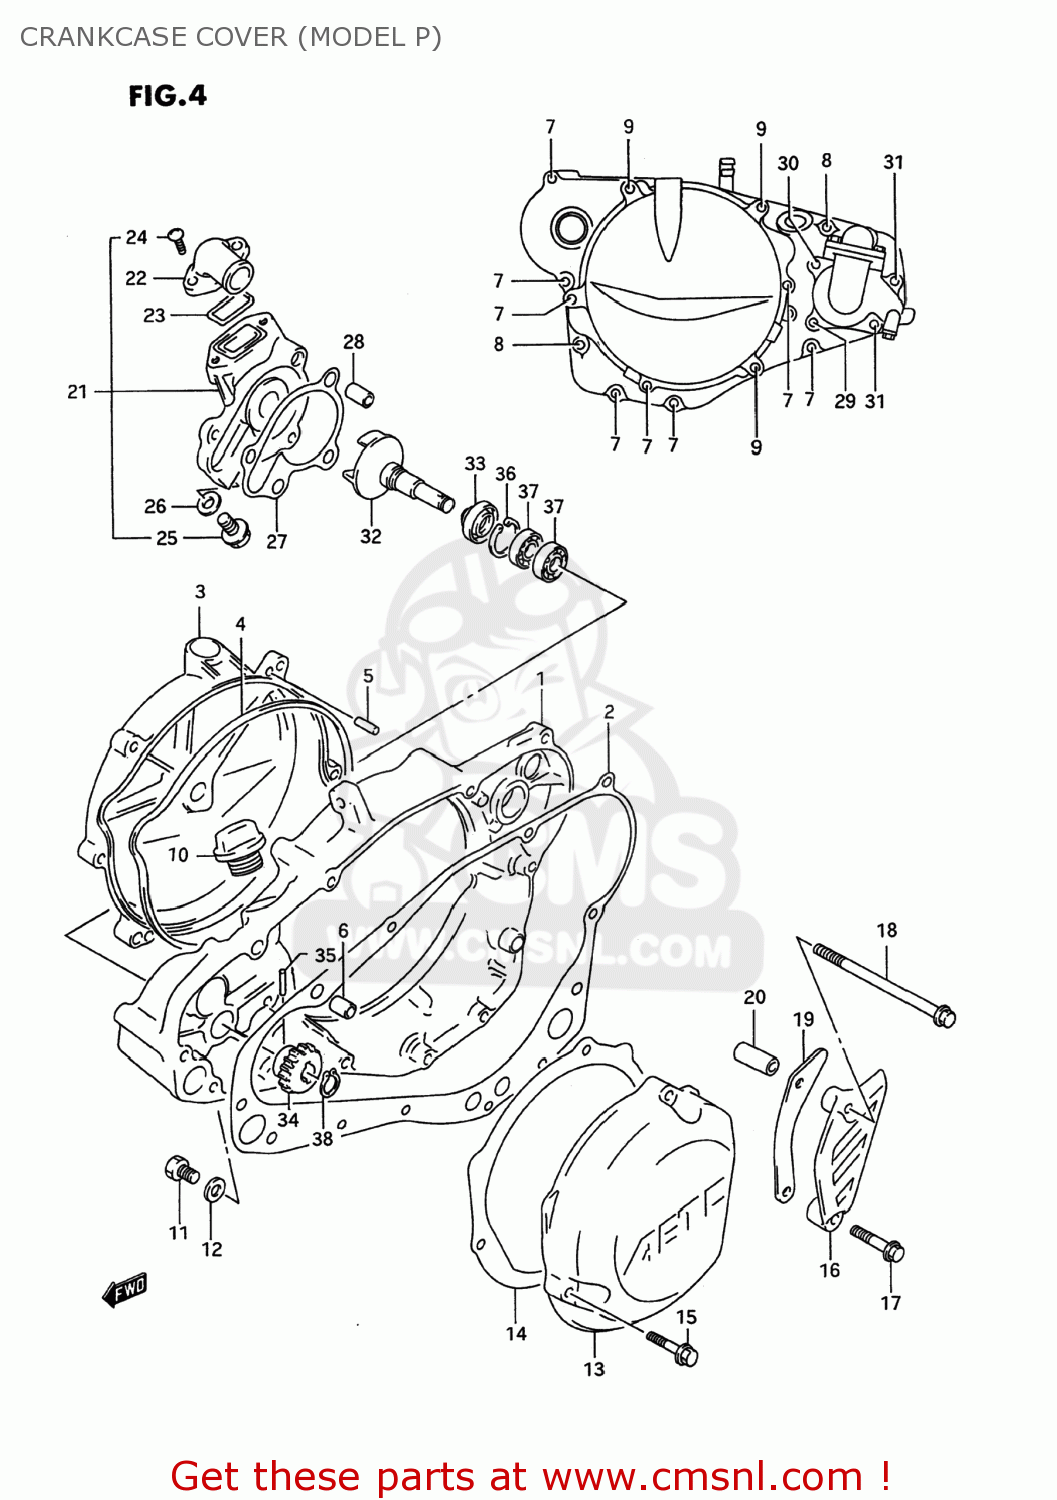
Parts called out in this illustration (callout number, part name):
1	COVER,CLUTCH
2	GASKET,CLUTCH COVER (NAS)
3	COVER,CLUTCH,OUTER
4	O RING,CLUTCH COVER OUTER
5	PIN
6	PIN
7	BOLT
8	BOLT
9	BOLT
10	PLUG SET
11	SCREW(6X10)
12	GASKET(6.2X11X1).2 (NAS)
13	COVER,MAGNETO
14	GASKET,MAGNETO COVER (NAS)
15	BOLT
16	COVER,ENGINE SPROCKET
17	BOLT
18	BOLT 6X95
19	PLATE,FR CHAIN GUIDE(13T)
20	SPACER(6.5X10.5X25)
21	CASE ASSY,WATER PUMP
22	CONNECTOR
23	O RING,WATER PUMP CONNECTOR
24	SCREW
25	BOLT
26	WASHER
27	GASKET,WATER PUMP CASE (NAS)
28	PIN
29	BOLT
30	BOLT
31	BOLT
32	IMPELLER,WATER PUMP
33	SEAL,WATER PUMP OIL
34	GEAR,WATER PUMP DRIVEN
35	PIN(3X13.8)
36	CIRCLIP
37	BEARING
38	CIRCLIP,10MM
